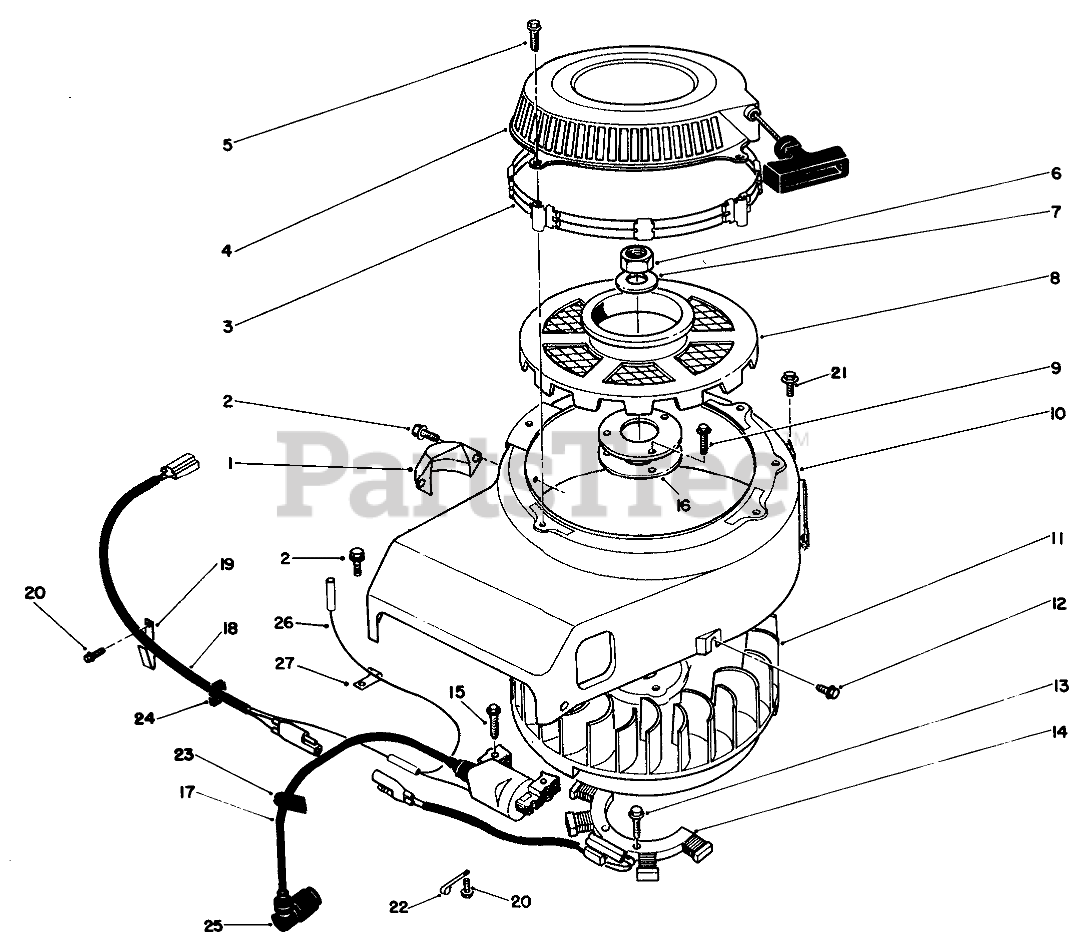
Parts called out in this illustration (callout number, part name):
4	Recoil Starter Assembly
5	BOLT-FLANGED (6X10)
9	Bolt-Flanged (8X12)
10	Housing-Fan
11	Flywheel
12	BOLT-FLANGED (6X10)
15	Bolt
17	Coil
20	Bolt-Flanged (6X10)
21	Bolt-Flanged (6X14)
25	Cap-Spark
26	Lead Wire
27	Clamp
